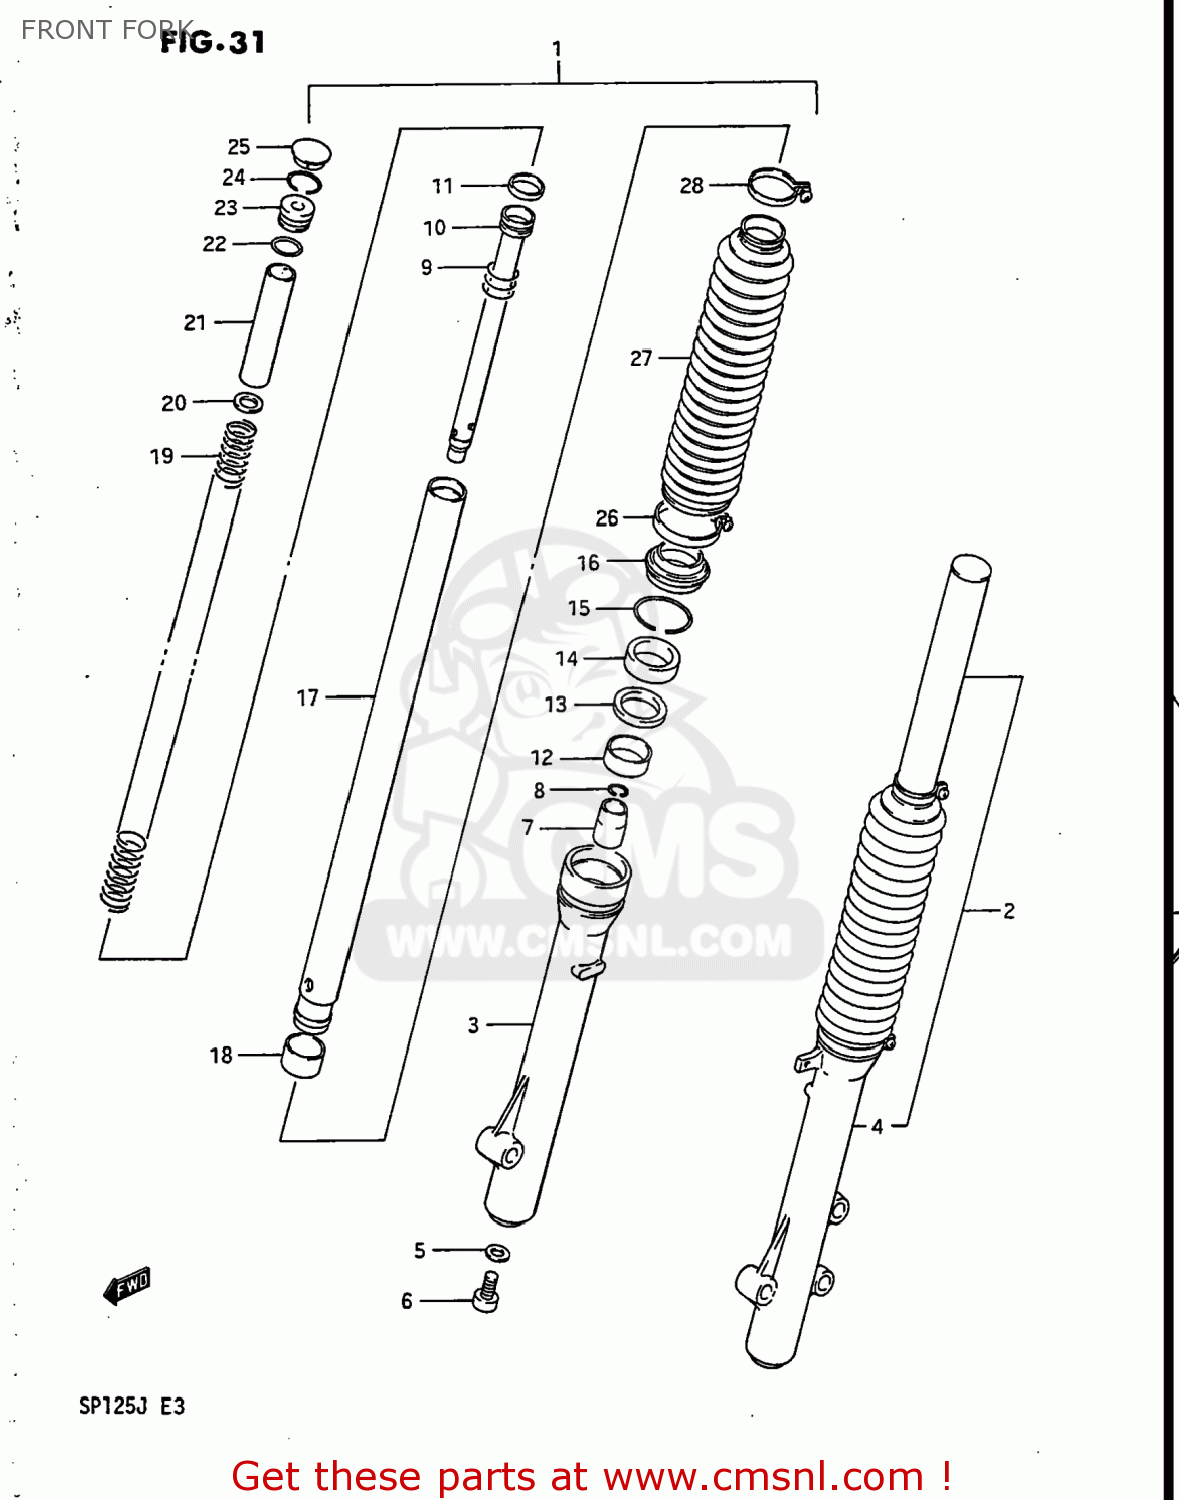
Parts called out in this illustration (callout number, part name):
1	DAMPER ASSY,FR FORK,R
2	DAMPER ASSEMBLY,LEFT
3	TUBE,OUTER,R
4	TUBE,OUTER,L
5	GASKET (NAS)
6	BOLT(8X27)
7	PIECE,OIL LOCK
8	RING,STOPPER
9	SPRING,REBOUND
10	CYLINDER,FRONT FORK
11	RING,PISTON
12	BUSH,GUIDE
13	SPACER,SEAL
14	OIL SEAL,FRONT FORK
15	CIRCLIP,FORK OIL SEAL
16	SEAL,DUST
17	TUBE,INNER
18	PISTON
19	SPRING
20	SPRING,JOINT
21	SPACER
22	O RING
23	SPRING SEAT B
24	RING,STOPPER
25	CAP
26	BAND
27	BOOT
28	BAND
